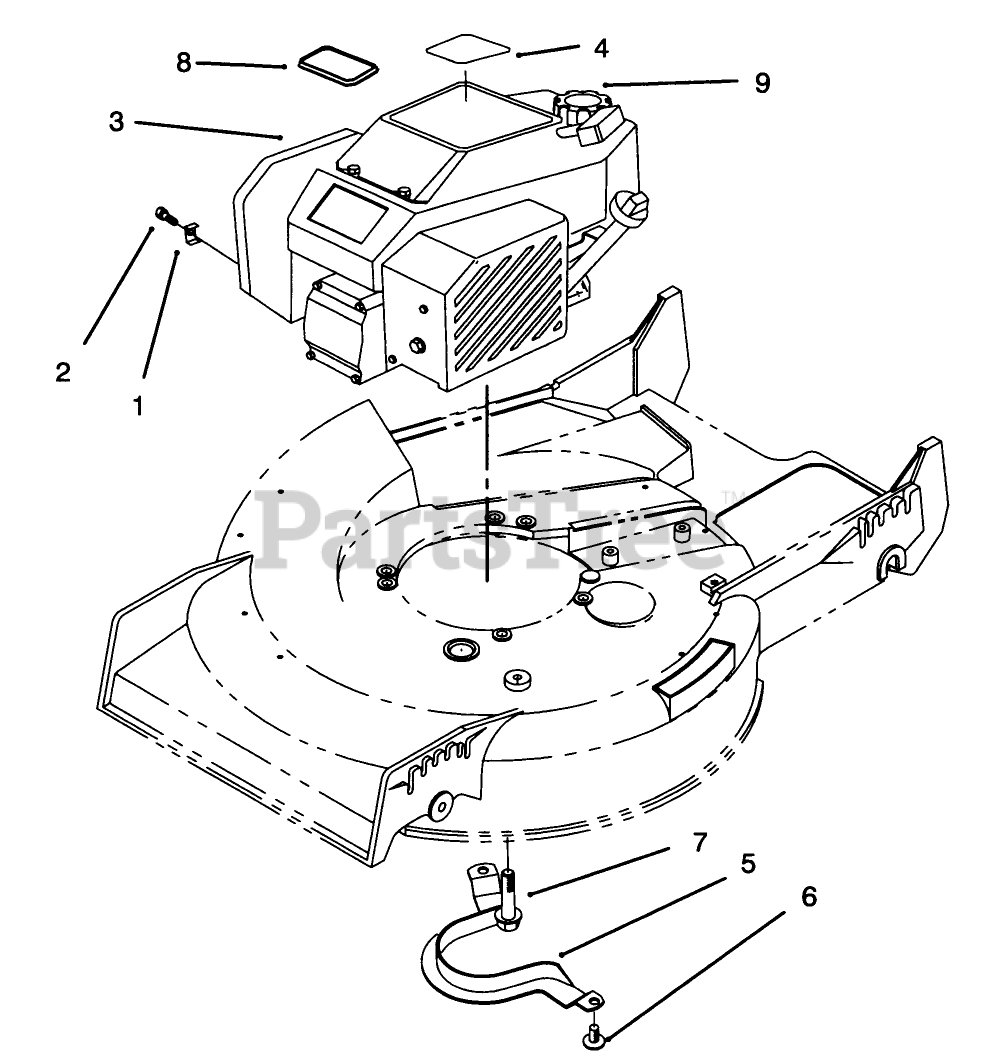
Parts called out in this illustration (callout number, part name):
1	CLAMP-CASING
2	Screw
3	Engine (Incl. Ref. #4 & 8)
4	DECAL - ENGINE
5	Guide-Belt
6	SCREW-HWH
7	SCREW-HWH
8	PLATE-LOGO
9	GAS CAP ASM
